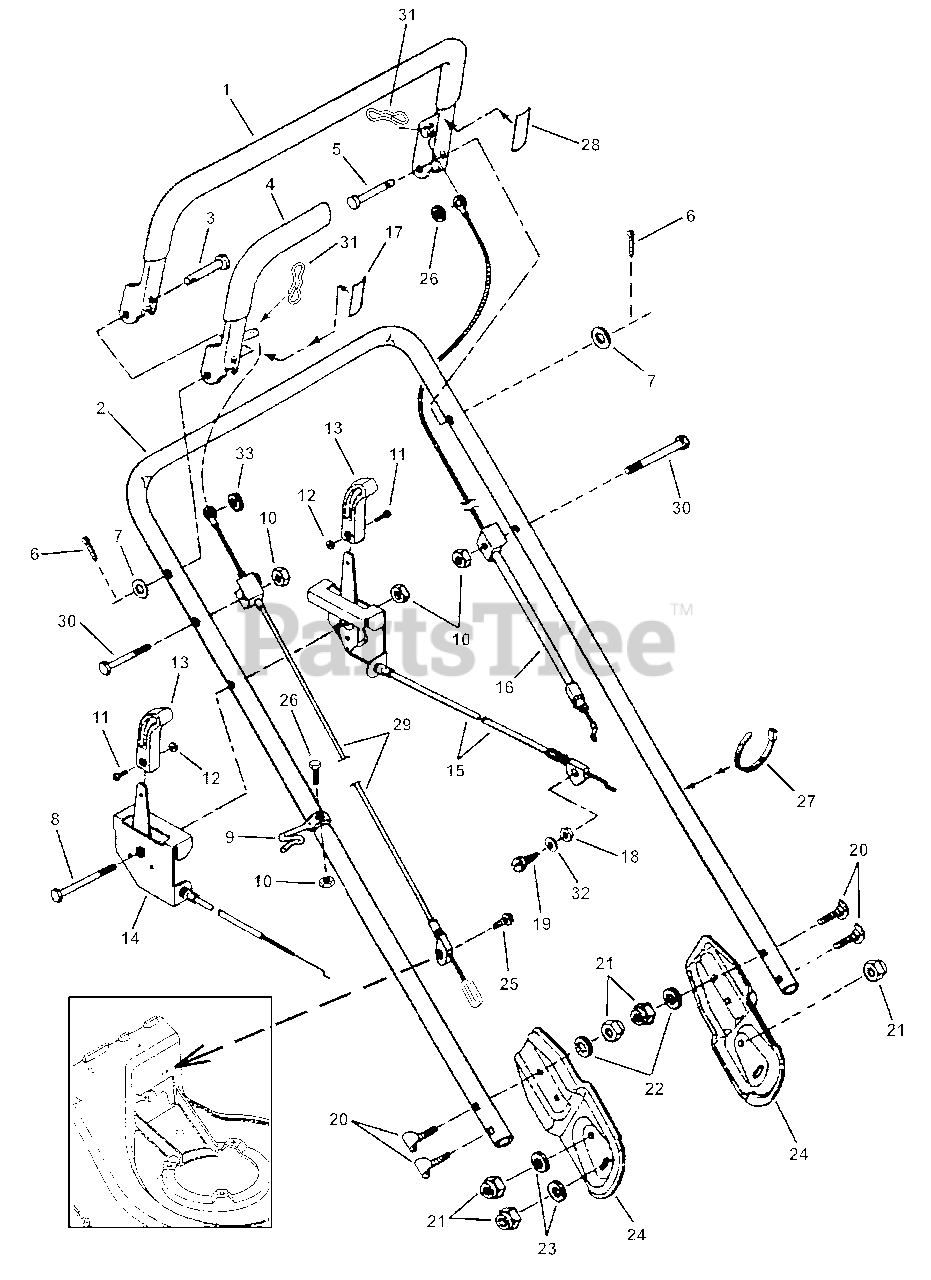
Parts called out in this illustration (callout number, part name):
1	CONTROL, Blade/Engine
2	HANDLE, Upper
3	PIN, 5/16 X 1.75 Clevis
4	BAIL, Traction (coated)
5	PIN, 5/16 X 1.42 Clevis
6	PIN, 3/32 x 1/2" Cotter
7	WASHER, 5/16" Flat
8	SCREW, 1/4-20 x 2-1/2" Hex Head Cap, GR5
9	GUIDE, Pull Rope
10	NUT, 1/4-20 Hex Nyloc
11	SCREW, #8-32 x 3/8" Fillister Head
12	NUT, #8-32 Hex
13	KNOB, Engine Speed Control & Ground Speed Control
14	CONTROL, Engine Speed (Robin 6HP Engine)
15	CONTROL, Ground Speed
16	CABLE, Blade/Engine Control (Robin Engine)
17	DECAL, Ground Drive
18	NUT, #10-24 Hex Center Lock
19	SCREW, #10-24 x 3/4" Pan Head Machine
20	BOLT, 5/16-18 x 1-1/2" Curved Head Carriage
21	NUT, 5/16-18 Hex Nyloc
22	WASHER, 5/16" Internal Tooth Lock
23	WASHER, 11/32" Flat
24	BRACKET, Handlebar
25	SCREW, #10-24 x 5/8" Slotted Hex Washer Head Self-Tap
26	SCREW, 1/4-20 x 1-1/2" Hex Head Cap GR5
27	TIE,Wire 1.29" Long Black
28	DECAL, Operator Presence Control
29	CABLE, Wheel Drive Control
30	SCREW, 1/4-20 x 2" Hex Head Cap GR5
31	COTTER PIN, Bow-Tie Locking
32	WASHER, 7/32" Flat
33	WASHER, 3/16" Flat
